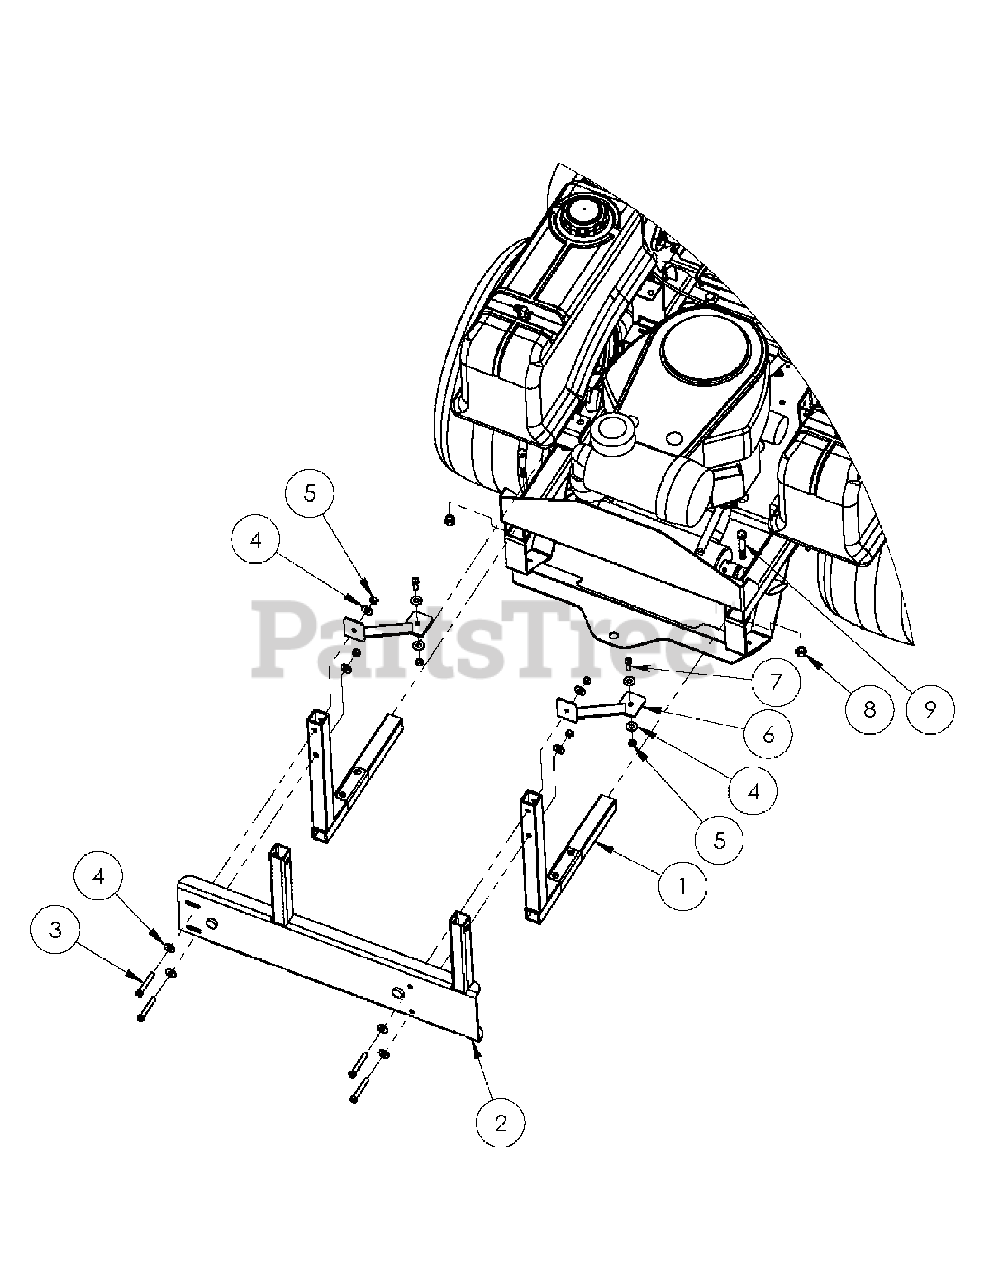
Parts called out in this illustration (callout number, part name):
1	SIDE SUPPORT
2	CATCHER MOUNTING PANEL
3	CAP SCREW-3/8-16 X 2 1/2" LONG
4	3/8" FLAT WASHER
5	HEX NUT, NYLON INSERT-3/8"-16
7	CAP SCREW-3/8-16 X 1" LONG
8	Purchase Locally
9	Purchase Locally
